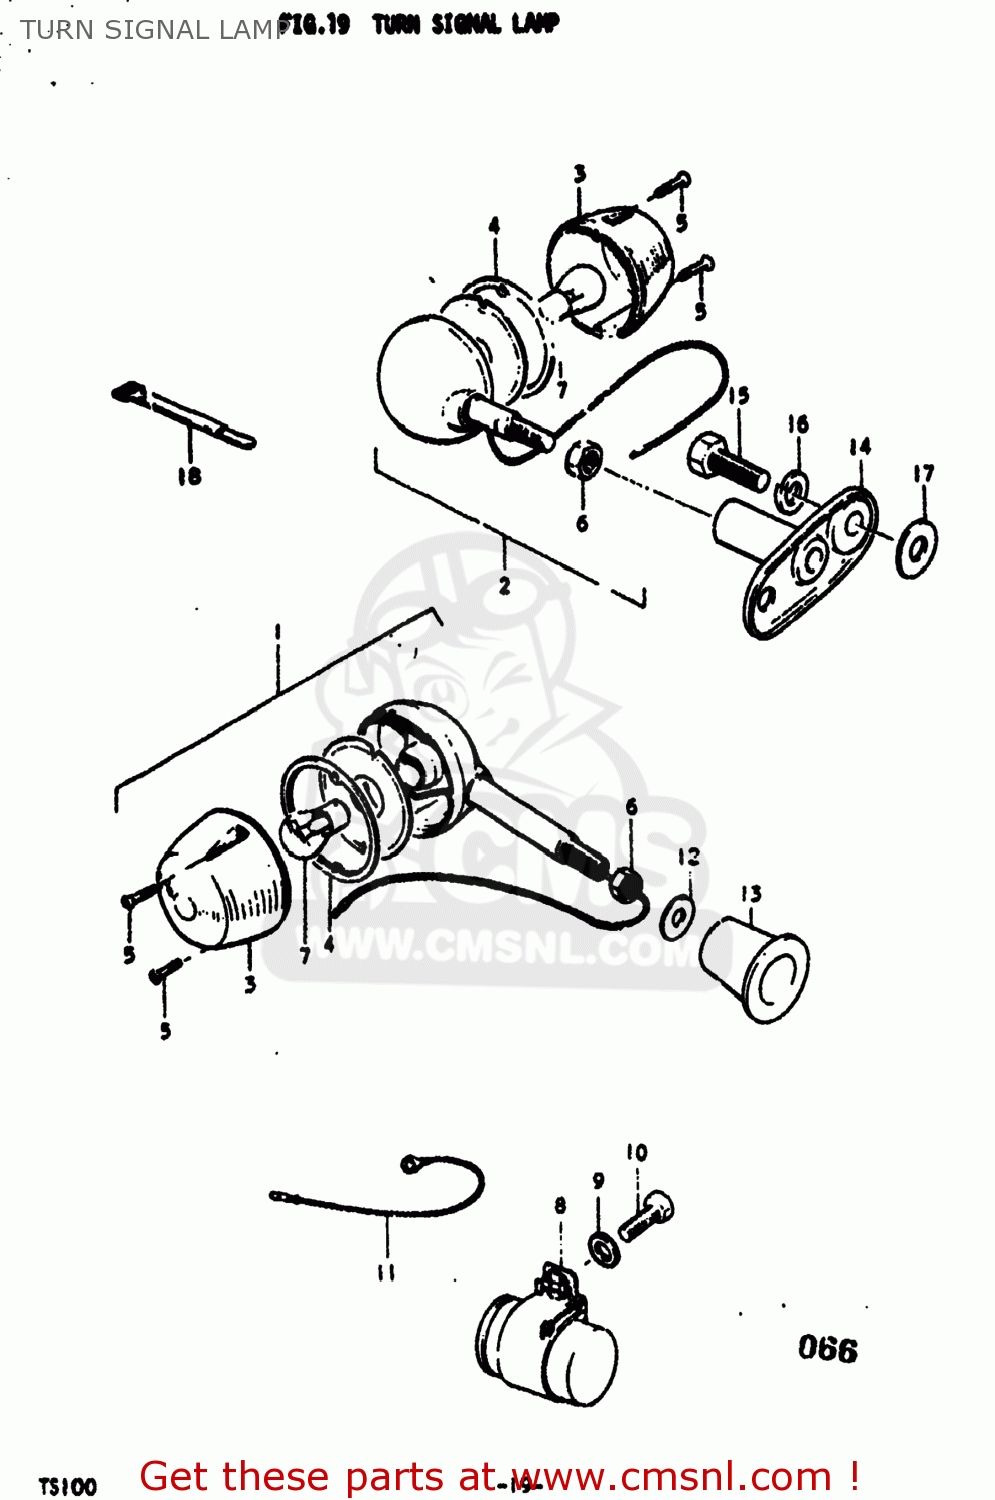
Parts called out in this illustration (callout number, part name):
1	LAMP ASSEMBLY,FRONT TURN SIGNAL
2	TURN SIGNAL ASSY, FRONT B
3	LAMP ASSEMBLY,REAR TURN SIGNAL
4	LAMP ASSEMBLY,REAR TURN SIGNAL
5	LENS
6	GASKET (NAS)
7	SCREW
8	GASKET (NAS)
9	NUT
10	BULB(6V17W,STANLEY,A4513A)
11	CLAMP
12	CUSHION
13	SPACER,RR TURNSIGNAL LAMP
14	WASHER (10.5X30X2.3)
15	LOCK WASHER
16	NUT
17	LEAD WIRE,EARTH
